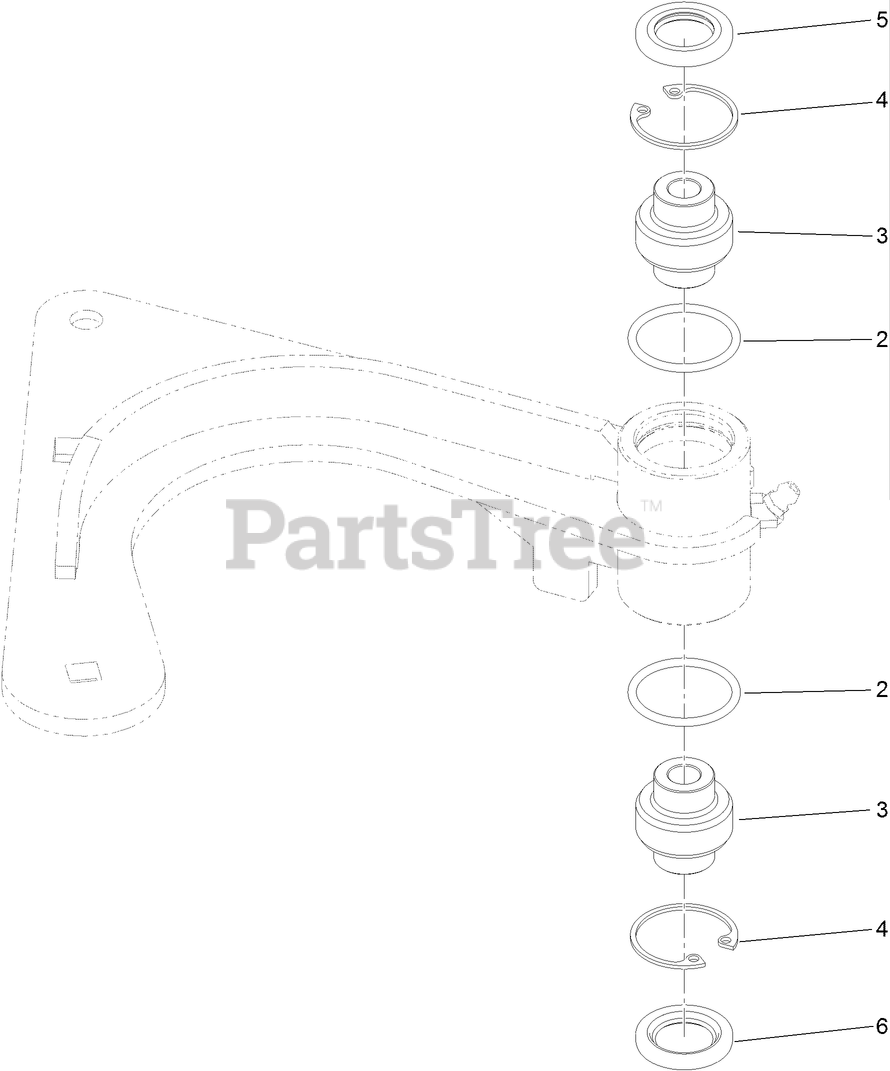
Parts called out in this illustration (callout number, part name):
2	O-RING
3	BEARING-SPHERICAL
4	RING-SNAP
5	SEAL-LIP, DOUBLE
6	SEAL-LIP, SINGLE
